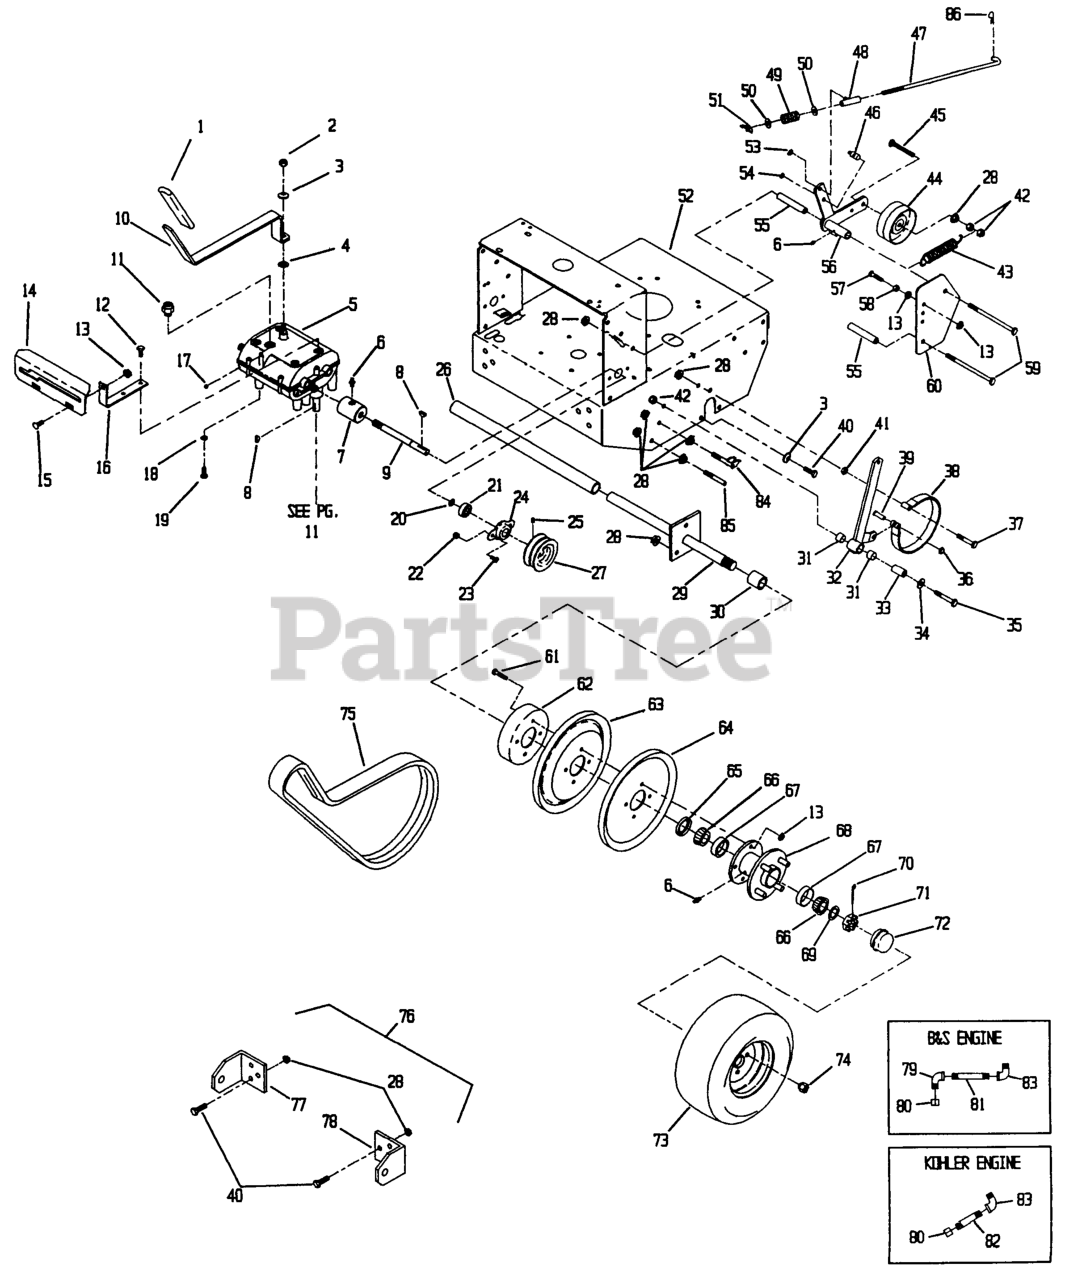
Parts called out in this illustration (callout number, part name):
9	SHAFT-TRANSMISSION
11	SWITCH-START, NEUTRAL
16	BRACKET-PLATE, SHIFT
17	BALL,DETENT (SERVICE ONL
18	WASHER-LOCK
21	BEARING-SHAFT
24	FLANGE-OUTPUT
25	SCREW-SET
26	SLEEVE,AXLE
30	SPACER,WHEEL SHORT
31	SLEEVE-BUSHING
33	BUSHING-PIVOT
36	RING-RETAIN,PUSH,EXT,FLAT
38	BAND-BRAKE
39	PIN-CLEVIS
43	SPRING-EXTENSION
44	IDLER-WHEEL, DRIVE
46	SWIVEL-SHORT, ADJUSTABLE
47	LINKAGE-BRAKE
49	SPRING-COMPRESSION
51	WINGNUT-NYLOCK
52	Deck, Weldmt Engine
55	SPACER-SHIELD
56	WLD,ARM RH
60	SHIELD,WHEEL DRIVE
62	DRUM-BRAKE
63	SHEAVE,WHEEL DRIVE
64	SHEAVE,WHEEL DRIVE
65	SEAL-GREASE
66	Cone-Bearing Tapered Roller
67	CUP-BEARING
68	HUB/WHEEL ASM
69	WASHER-SPACER
70	PIN-COTTER
71	NUT-SHH
72	CAP-GREASE
75	BELT,WHEEL DRIVE BANDED
76	Kit, Sulky Hitch
78	BRACKET,SULKY RH
79	ELBOW-90 DEG
80	CAP-HEX
81	NIPPLE
82	NIPPLE
83	FITTING-ELBOW-90
84	SCRAPER
86	PIN-COTTER
